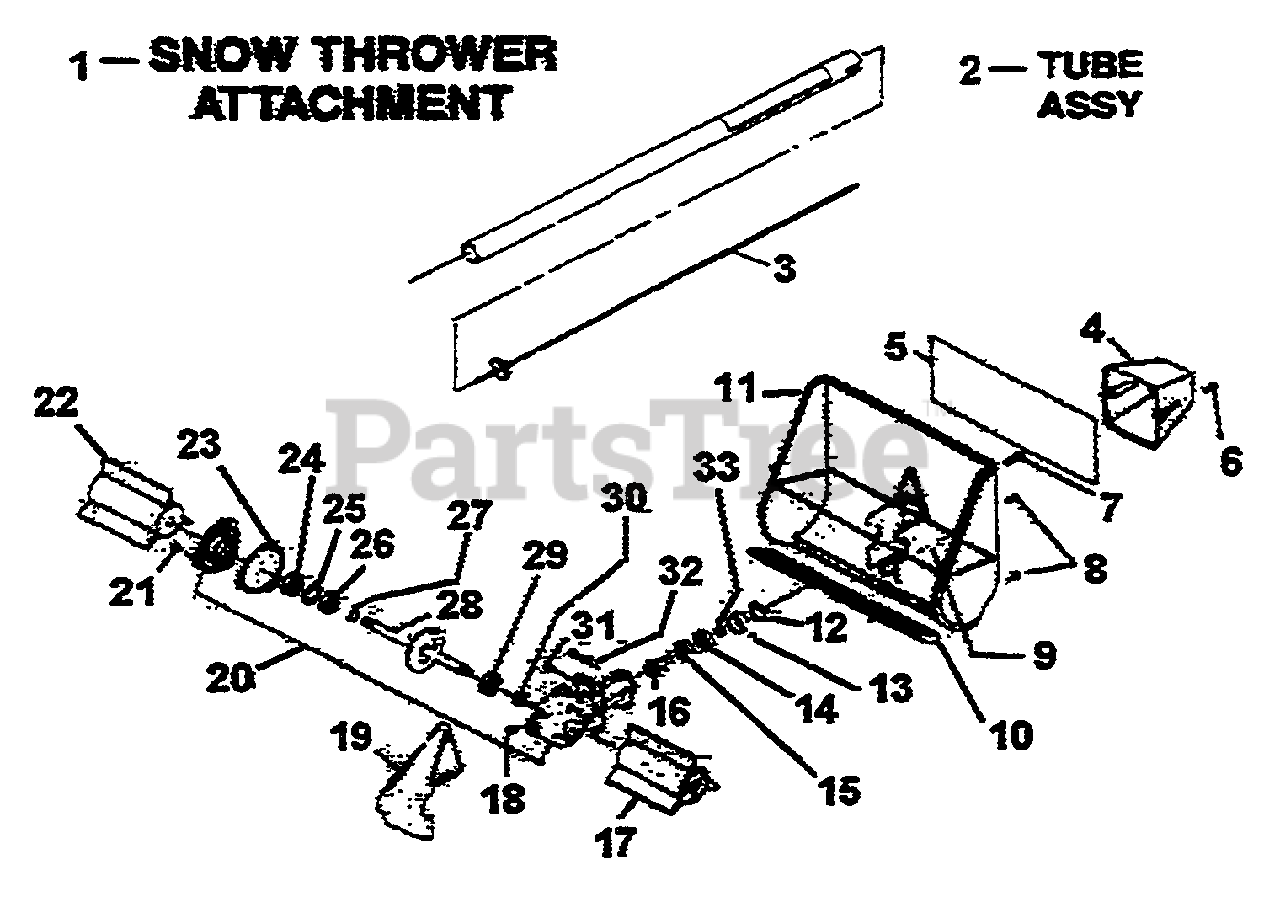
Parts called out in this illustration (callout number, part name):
1	SNOW THROWER ATTACHMENT
2	TUBE ASSY
3	FLEX CABLE
9	PLATE
10	SCRAPER BAR
12	SNAP RING
15	BEARING
16	PINION GEAR
17	ROTOR R.H.
20	GEAR CASE ASSY
22	ROTOR L.H.
28	SHAFT & GEAR
33	SNAP RING
